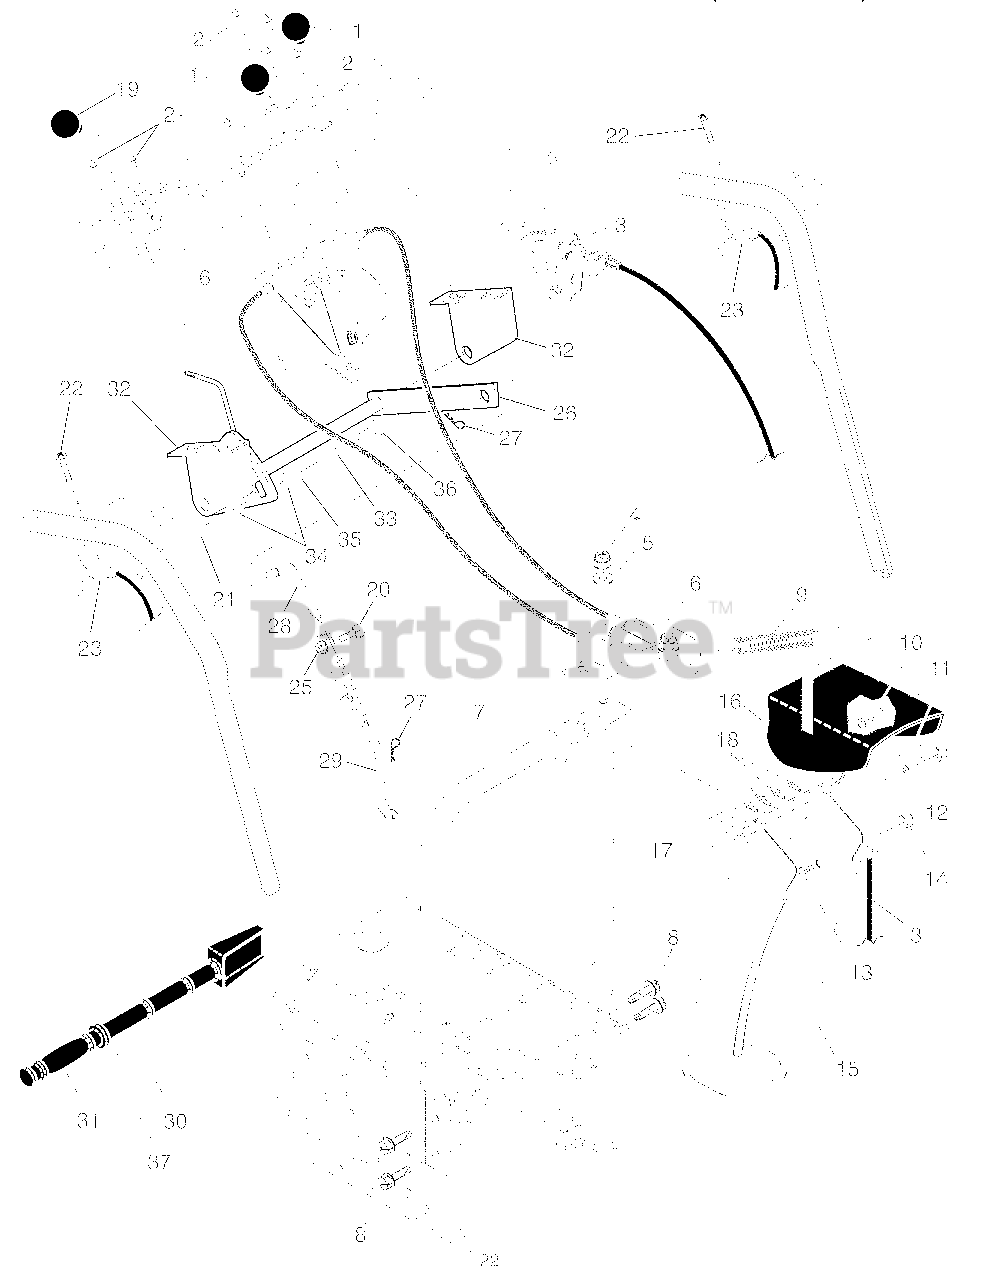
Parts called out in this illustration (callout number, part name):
1	Knob, Lever
2	Screw #10-24 x 5/8
3	Control Assembly, Deflector
4	Nut, Lock 3/8-16
5	Washer, Flat 3/8
6	Control Assembly, Chute Rotater
7	Support, Pivot
8	Screw, Hex Head 5/16-18 x 3/4
9	Spring, Deflector
10	Bolt, Shoulder
11	Washer, Friction, Nylon
12	Nut, Lock 1/4-20
13	Bolt, Carriage 5/16-18
14	Nut, Hex, Flanged
15	Chute Assembly
16	Defl ector Assembly
17	Seal, Deflector
18	Rivet, Blind
19	Knob, Speed Control Lever
20	Bolt, Carriage 5/16-18 x 3/4
22	Screw #10-24 x 1-1/2
23	Control Assembly, Power Steering
25	Nut, Lock 5/16-18
26	Lever Assembly, Speed Control
27	Retainer, Hairpin
28	Rod, Upper, Speed Control
29	Rod, Lower, Speed Control
30	Clamp, Clean-Out Tool
31	Tool, Clean-Out
32	Bracket, Shift, Hydro
35	Washer, Friction
